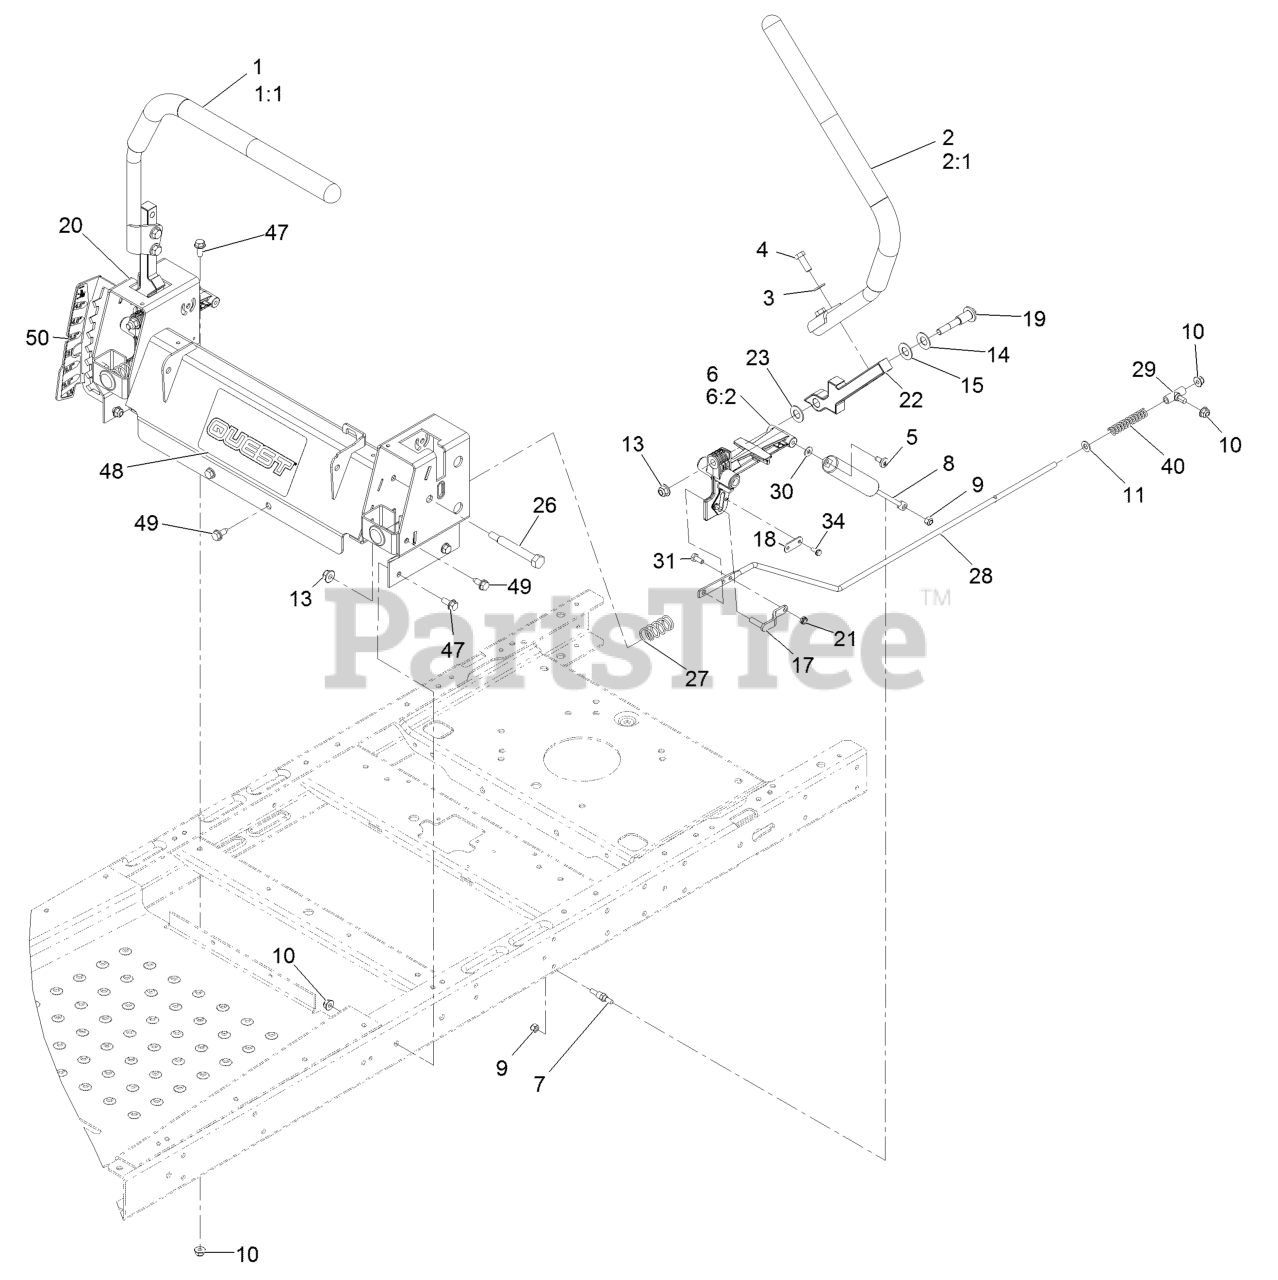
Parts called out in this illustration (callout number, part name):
1	HANDLE-CONTROL, RH
2	HANDLE-CONTROL, LH
3	WASHER-FLAT
4	SCREW-HH
5	SCREW-SHOULDER
6	ACTUATOR ARM ASM
6:2	BUSHING-FLANGE
7	STUD-DAMPER
9	NUT-LOCK, NI
10	NUT-HF, NI
11	WASHER-PLAIN
13	NUT-HF, NI
14	WASHER-BELLEVILLE
18	PLATE-STOP, HYDRO
19	BOLT-PIVOT
20	Control Box ASM
21	NUT-LOCK, NI
23	WASHER-NYLON
26	BOLT-PIVOT
27	SPRING-RETURN
28	ROD-HYDRO
29	MOUNT-ROD, HYDRO
31	SCREW-HH
34	SCREW-TAPTITE
40	SPRING-RETURN, NEUTRAL
47	SCREW-HHF
48	DECAL-QUEST
49	Screw-HWH 5/16-18 X 3/4 Tf
50	DECAL-HOC
